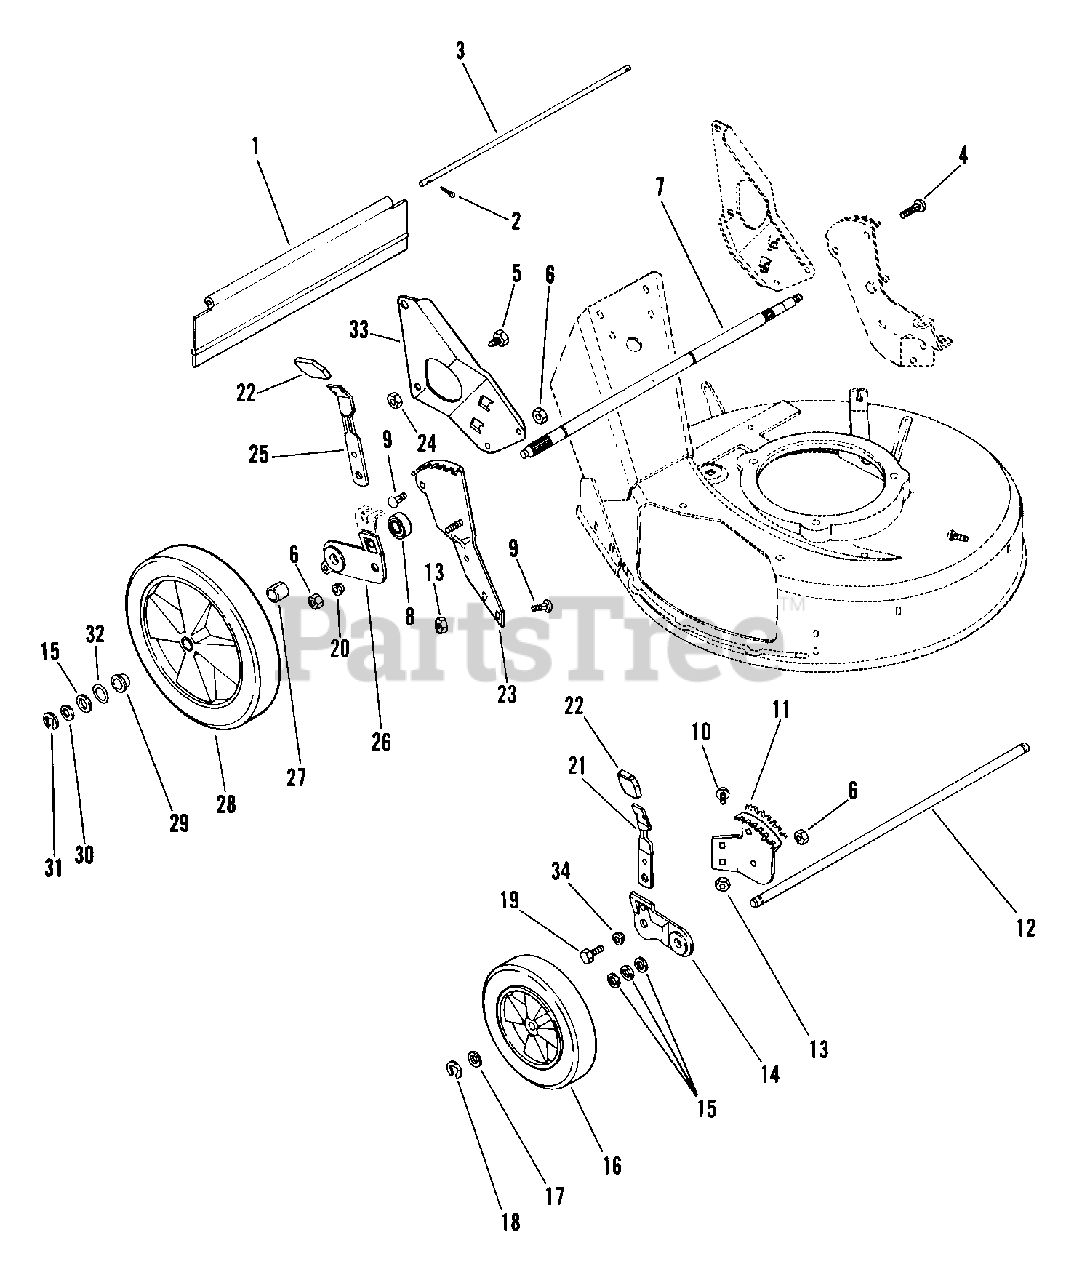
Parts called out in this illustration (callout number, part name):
1	REAR PROTECTIVE GUARD, PUSH
1	REAR PROTECTIVE GUARD, S.P.
2	PIN-COTR .06X.50
3	ROD
4	BLT-RDHDSQNK .31-18X1.0 SHT PL
4	BLT-RDHDSQNK .31-18X1.25 SHTPL
5	HANDLEBAR STUD
5	BLT-HEX .31-18X.75 PL GR5
6	NUT-LK .312-18 GR A PL
7	REAR AXLE,5/8 DIA
7	REAR AXLE - PUSH MOWER
8	BRG-BALL .625X1.383X.50
9	BLT-RDHDSQNK .312-18X.62SHTPL
10	BLT-RDHDSQSHNK .31-18X.50 YZ
11	L.H. FRONT QUADRANT
11	R.H. FRONT QUADRANT
12	FRONT AXLE
13	NUT-FLG. .312-18 PL
14	LEFT ADJUSTOR BRACKET ASSEMBLY
14	RIGHT ADJUSTOR BRACKET ASSEMBL
14	R.H. FRONT ADV. BRACKET ASSEM.
15	WSHR-FL-STL .520X.827X.062 YZ
16	WHEEL
17	WSHR-FL-STL .505X.880X.072 PL
18	RG-RTNG-EXT .438X.035
19	BLT-HEX .31-18X.88 PL GR2
20	BSHG-FLG .32X.500X.344X.880
21	FRONT HEIGHT ADJUSTMENT LEVER
23	QUADRANT, REAR - L.H.
23	REAR QUADRANT, R.H.
24	NUT-LK-JAM-CTR .375-16 PL
25	HEIGHT ADJUSTMENT LEVER
26	REAR BRACKET & BEARING ASSEMBL
26	REAR BRACKET & BEARING ASSY RH
26	R.H. REAR ADJUSTOR BRACKET
26	REAR ADJUSTMENT BRACKET L.H.
26	L.H. REAR ADJUSTOR BRACKET
27	SPACER TUBE,PUSH LH
27	SPACER TUBE PUSH RH
27	SPACER TUBE, SELF PROPEL
28	WHEEL
28	LH WHEEL
28	RH WHEEL
28	10 1/2 TIRE SKIN
29	BSHG-SLV .625X.750X.500
30	WSHR-FL-STL .630X1.005X.062 PL
31	RG-RTNG-EXT .500X.042 (E)
32	SEAL .625X.875X.125
33	RH HANDLEBAR MTG. BRKT.
33	LH HANDLEBAR MTG. BRKT.
34	BSHG-FLG .32X.500X.344X.880
34	BSHG, FLG .325X.499X.26X.88
